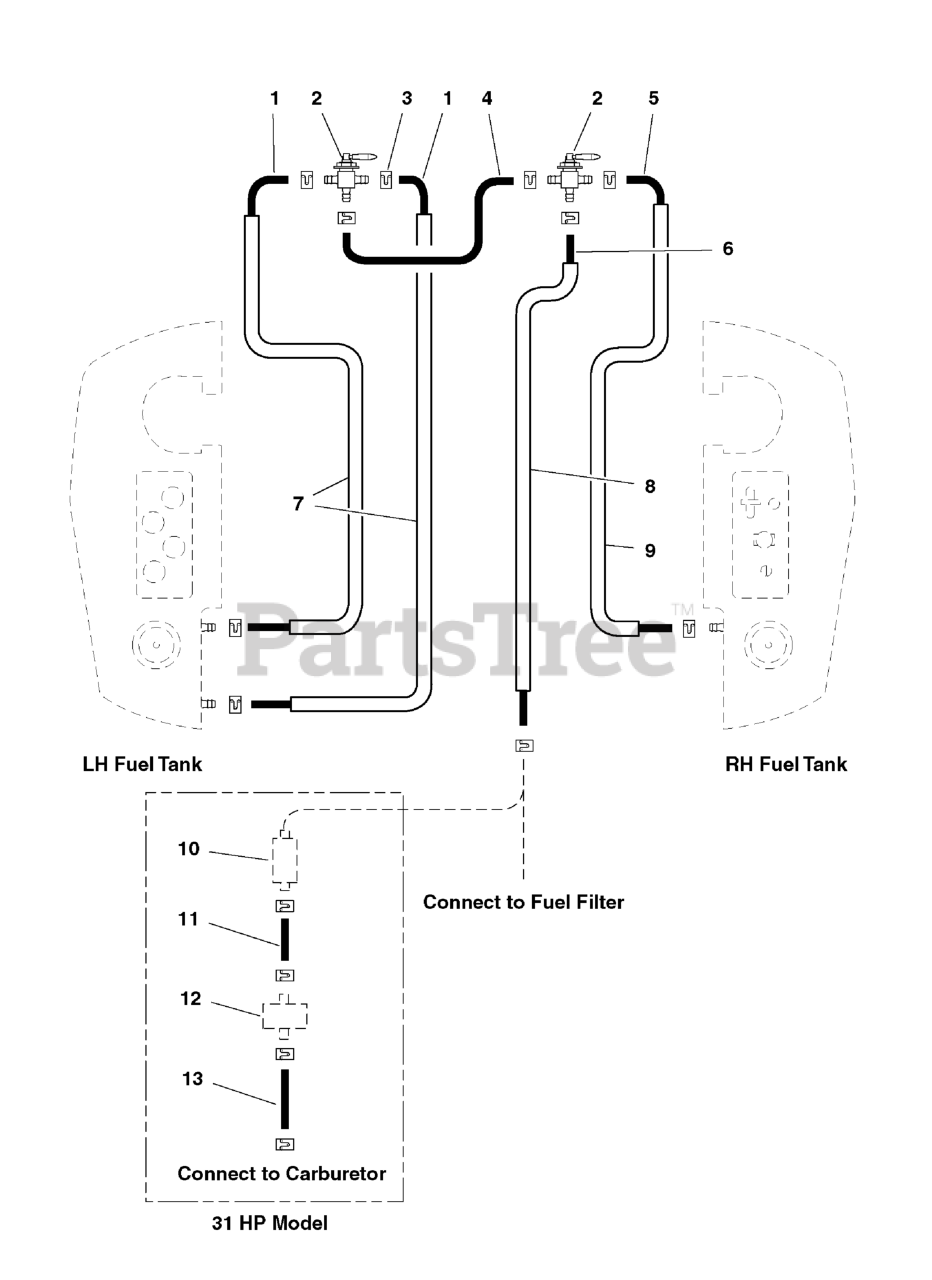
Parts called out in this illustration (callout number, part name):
1	1/4" Fuel Line, 44" Long
2	VALVE, Fuel Shut Off
3	CLAMP, Hose
4	1/4" Fuel Line, 8" Long
5	1/4" Fuel Line, 48" Long
6	1/4" Fuel Line, 52" Long
7	WIRE LOOM, 43"
8	WIRE LOOM, 51"
9	HOSE, 1/4" FUEL, 47.00"
10	FUEL FILTER
11	1/4" Fuel Line, 2" Long
12	FUEL PUMP
13	1/4" Fuel Line, 24" Long
